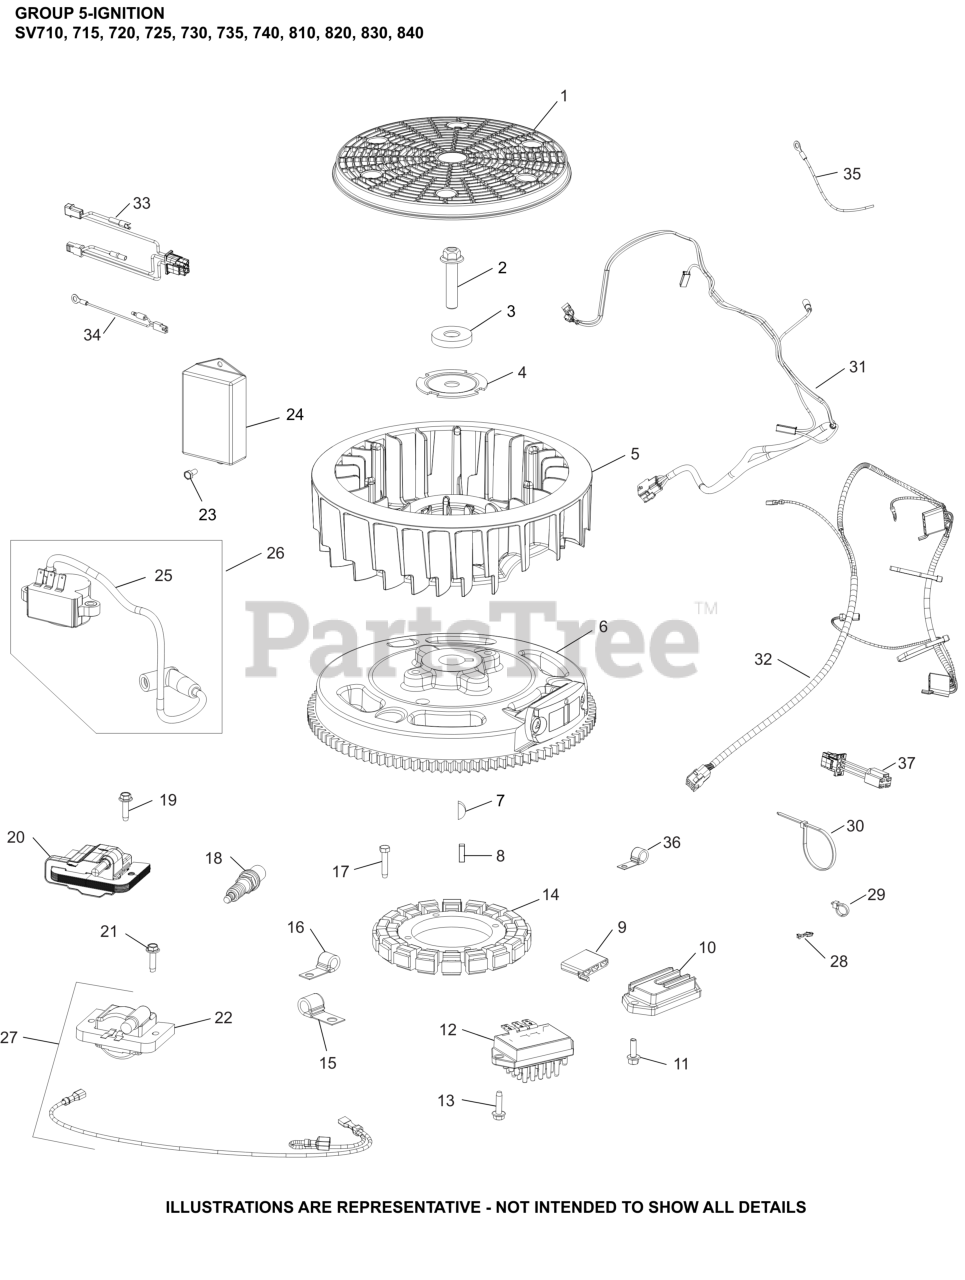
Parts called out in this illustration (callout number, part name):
1	SCREEN, GRASS
2	SCREW, HEX FLANGE
3	WASHER, FLAT
4	PLATE, FAN MOUNTING
5	FAN-USE 32 755 38-S
6	FLYWHEEL ASSEMBLY
8	KEY, SQUARE
9	CONNECTOR
10	REGULATOR/RECTIFIER-(#2540337S)
13	SCREW, THD FRM-USE 25 086 473-S
14	KIT, 15 / 20 AMP STATOR
17	SCREW, THREAD FORMING
18	PLUG, SPARK (STD)
20	MODULE,IGNITION
22	MODULE, MDI-USE 32 584 08-S
24	MODULE,DSAM CONTROL-DISC-SEE PB 259
25	MODULE,DSAI IGNITION-DISC-SEE PB 259
26	KIT,DSAI CONVERSION-DISC-SEE PB 259
27	KIT,MDI MODULE CONVERSION-SEE PB 259
31	HARNESS, WIRING
34	LEAD, JUMPER
NI	CLIP, CABLE (KM)
